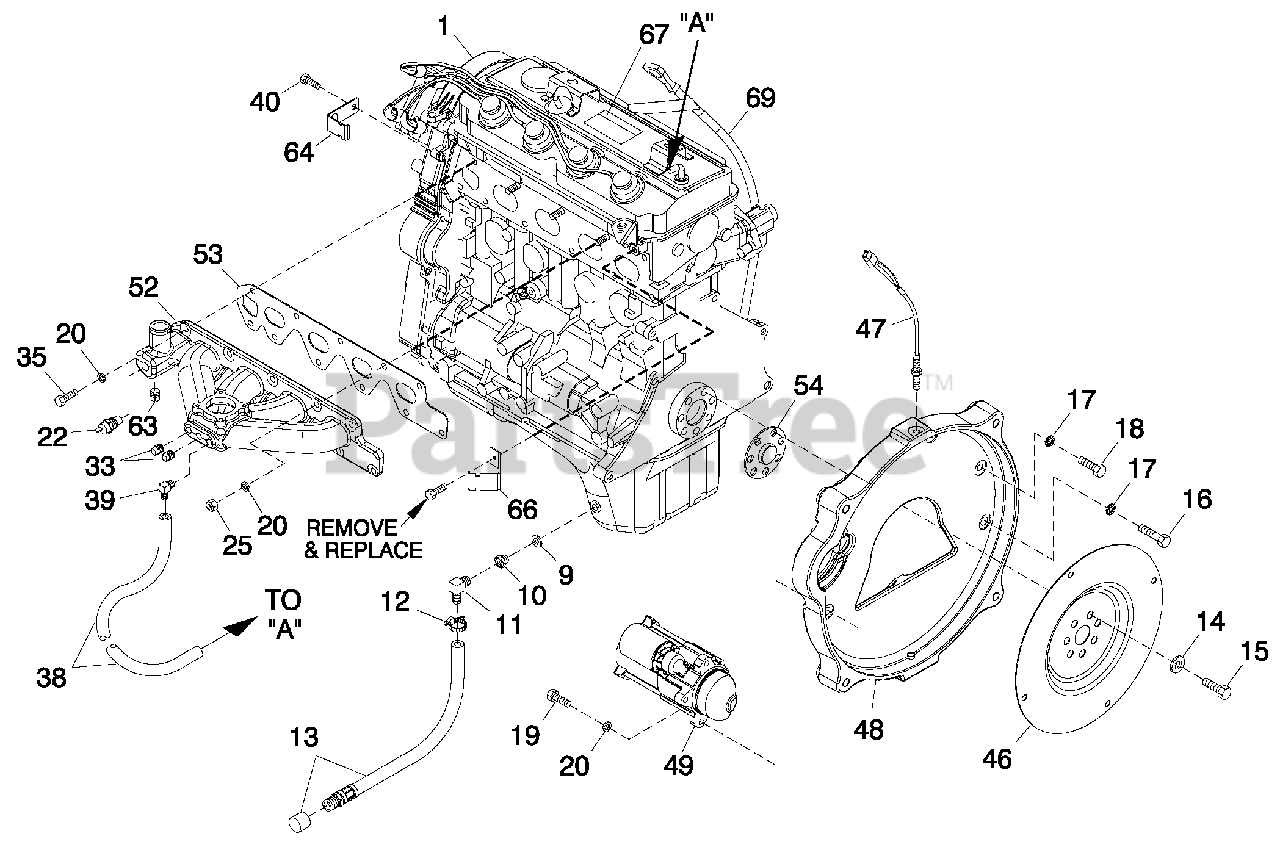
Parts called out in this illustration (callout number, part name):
1	ENGINE 2.4LG2 4G64 CERT
2	WASHER LOCK M10
3	SCREW HHCM8-1.25X 35 G8.8
4	SCREW SHC M14-1.5 X 35 G10.9
5	ALTERNATOR DC W/O UT P ULLEY
6	SPACER DC ALTERNATOR P ULLEY
7	ADAPTOR 1/8 NPTF TO 1/8 BSPT
8	SWITCH OIL PRESS URE 10 PSI 2 POL (R-PANEL)
9	WASHER NYLON .565
10	ADAPTER M14-1.50X 3/8 NPT
11	BARBED EL 90 3/8 NPT X 3/8
12	CLAMP HOSE .38-.87
13	HOSE DRAIN ASSY 28"
14	WASHER FLAT .531 ID X 1.062 OD
15	SCREW HHCM12-1.25X 20 G10.9
16	SCREW HHC M10-1.25 X 45 G8.8
17	WASHER SHAKEPROOF EXT 7/16 STL
18	SCREW HHC M10-1.25 X 30 G8.8
19	SCREW SHC M8-1.25 X 30 G12.9
20	WASHER LOCK M8-5/16
21	SCREW THF M6-1 X 16 N WA Z/JS
22	SWITCH HI-TEMP 245D X 3/8 NPT (R-PANEL)
23	WASHER FLAT 5/16-M8ZINC
25	N UT HEX M8-1.25 G8 CLEAR ZINC
26	WASHER FLAT 3/8-M10ZINC
27	NUT HEX M6X1.0G8YELCHR
28	N UT HEX M10-1.25 G8YEL CHR
29	SCREW SHC M8-1.25X 25G12.9
30	WASHER LOCK M6-1/4
31	WASHER FLAT 1/4-M6 ZINC
32	SCREW HHC M6-1.0X 12 G8.8
33	PL U G STD PIPE 1/4 STEEL SQ HD
34	SCREW HHC M10-1.5X60G8.8
35	SCREW HHC M8-1.25 X 25 G10.9
36	OIL FILTER G2 ENGINE
37	COIL PACK
38	HOSE 3/8 ID SINGLE BRAID (15" LG)
39	BARBED EL 90 1/4 NPT X 3/8
40	SCREW HHC M6-1.0X25G8.8
44	GASKET EXHAUST MANIFOLD
45	EXHAU ST MANIFOLD G2 (MACHINE) (25KW, 35KW & 45KW)
46	FLEX PLATE 2 POLE 2.4L G2
47	ASSY MAGPICK UP(3/8-24 MALE)
48	ADAPTER ENGINE 2.4L MACHINE
49	STARTER MOTOR 12V
50	CAM SENSOR PIN ASSY
51	COVER CAM GEAR G2 REWORKED
52	MANIFOLD INTAKE (U SE HOSE 0G0816)
53	GASKET INTAKE MANIFOLD
54	SPACER 2.4L G2 FLEX PLATE
55	SHIELD HEAT G2
56	SHIELD HEAT SML
57	BRACKET COIL PACK
59	ADAPTER 2.4L CRANKSHAFT MACH
60	POLY V-BELT G2 (3600 RPM)
61	P ULLEY DC ALTERNATOR (3600 RPM)
62	SCREW HHC M6-1.0 X 35 G8.8 BLK
63	PLUG STD PIPE 3/8 STEEL SQ HD
64	BRACKET, SIGNAL CONDITIONER
65	SCREW HHC M8-1.25X70G8.8
66	BRACKET SIGNAL CONDITONER
67	DECAL SORE EPA CERTIFICATION
69	ROD ASSY OIL LEVEL GAUGE
70	O-RING SIZE 9.0MM X 2.0MM NITR
71	CABLE, SPARK PLU G, NO.1
72	CABLE, SPARK PLU G, NO.2
73	CABLE, SPARK PLU G, NO.3
74	CABLE, SPARK PLU G, NO.4
75	PLUG TAPER
